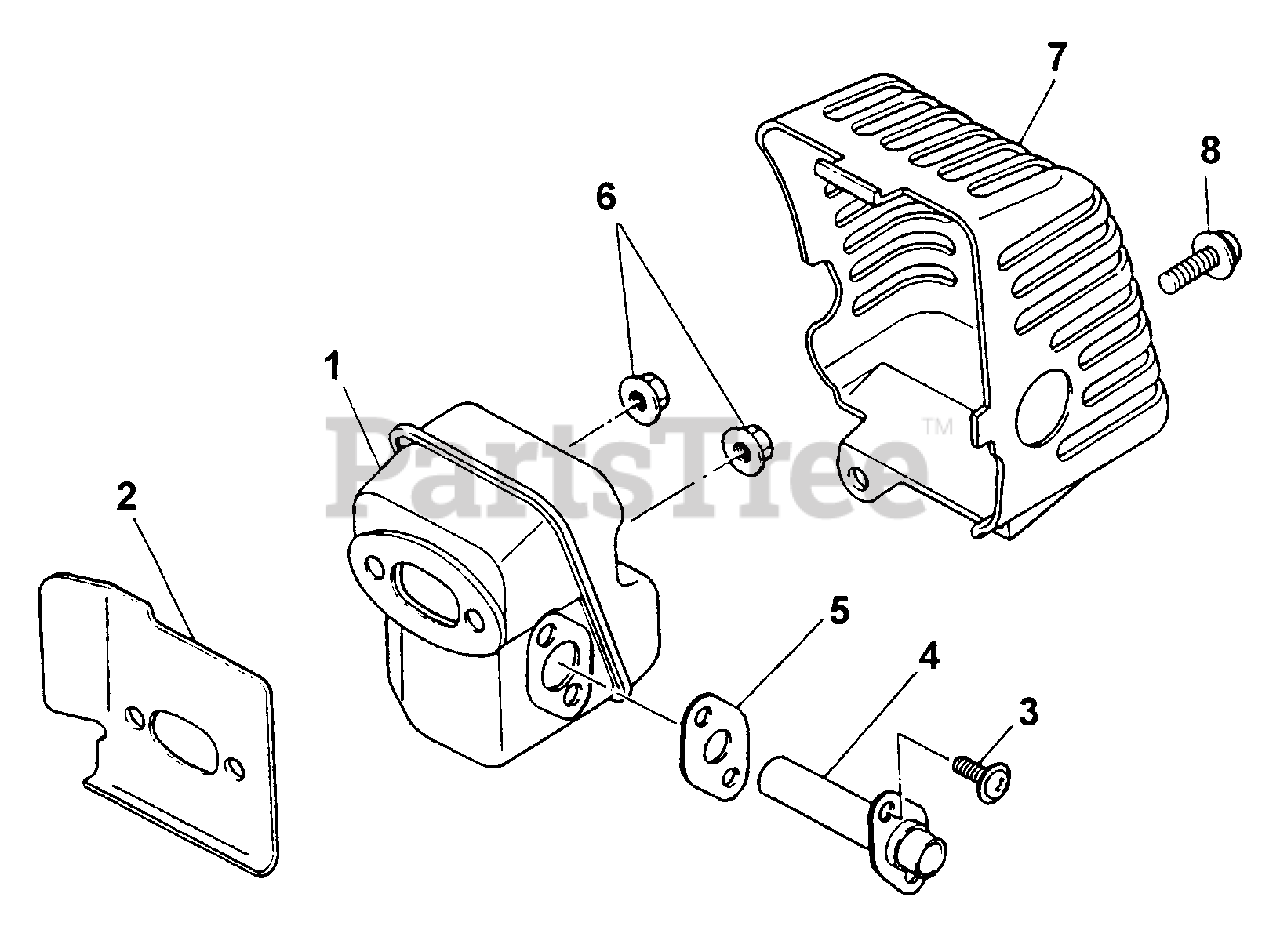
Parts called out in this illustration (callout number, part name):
1	MUFFLER ASSY
2	GASKET, MUFFLER
3	SCREW & WASHER
4	TAIL PIPE
5	GASKET, TAIL PIPE
6	NUT, FLANGE
7	COVER, MUFFLER
8	SCREW & WASHER
